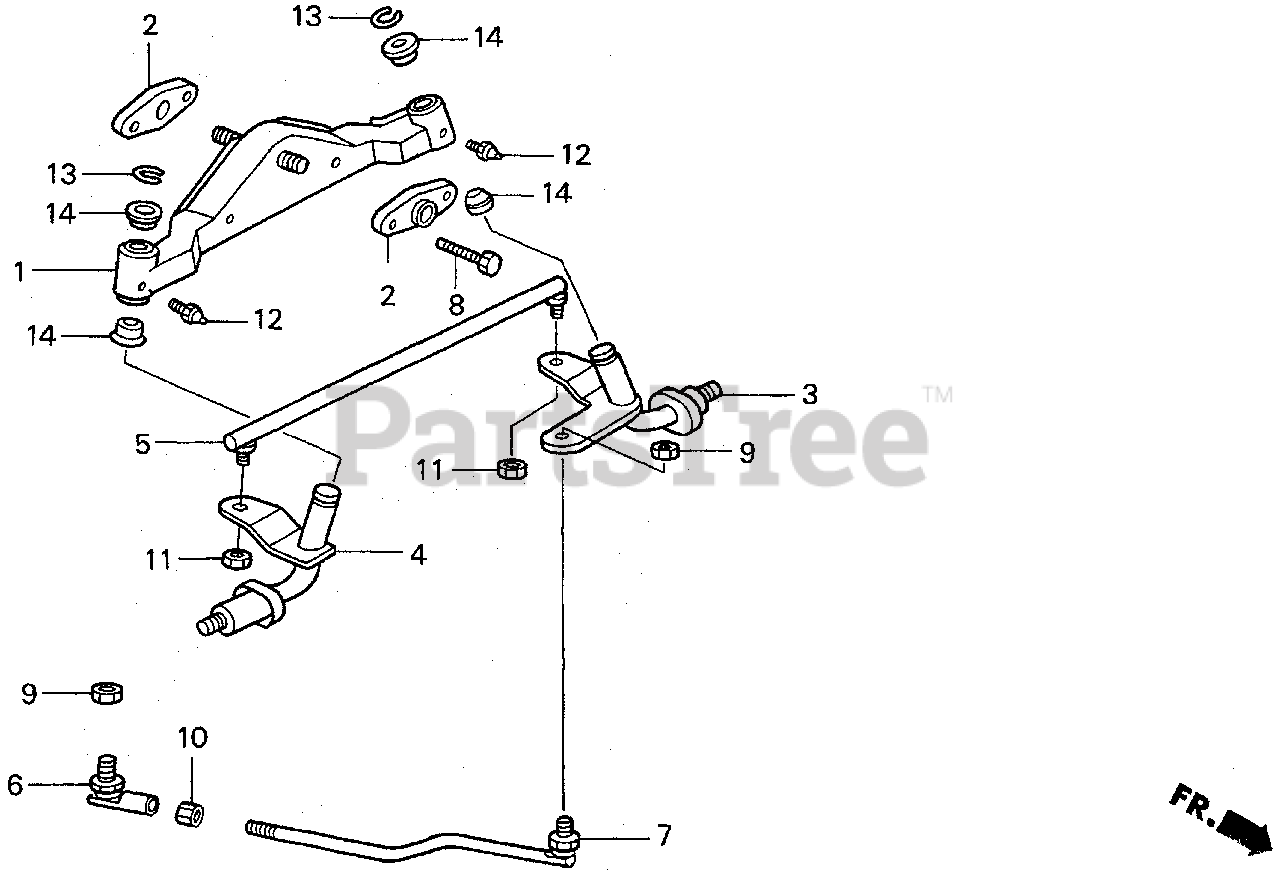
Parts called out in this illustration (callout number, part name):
2	PIVOT, FR. AXLE
3	KNUCKLE, L.
4	KNUCKLE, R.
6	JOINT, BALL
8	SCREW, CAP FLANGE
9	NUT, LOCK (7/16")
10	NUT, HEX. (1/2")
11	NUT, LOCK (3/8")
12	NIPPLE, STEERING GREASE
13	RING, WHEEL SNAP
14	BUSH, STEERING
